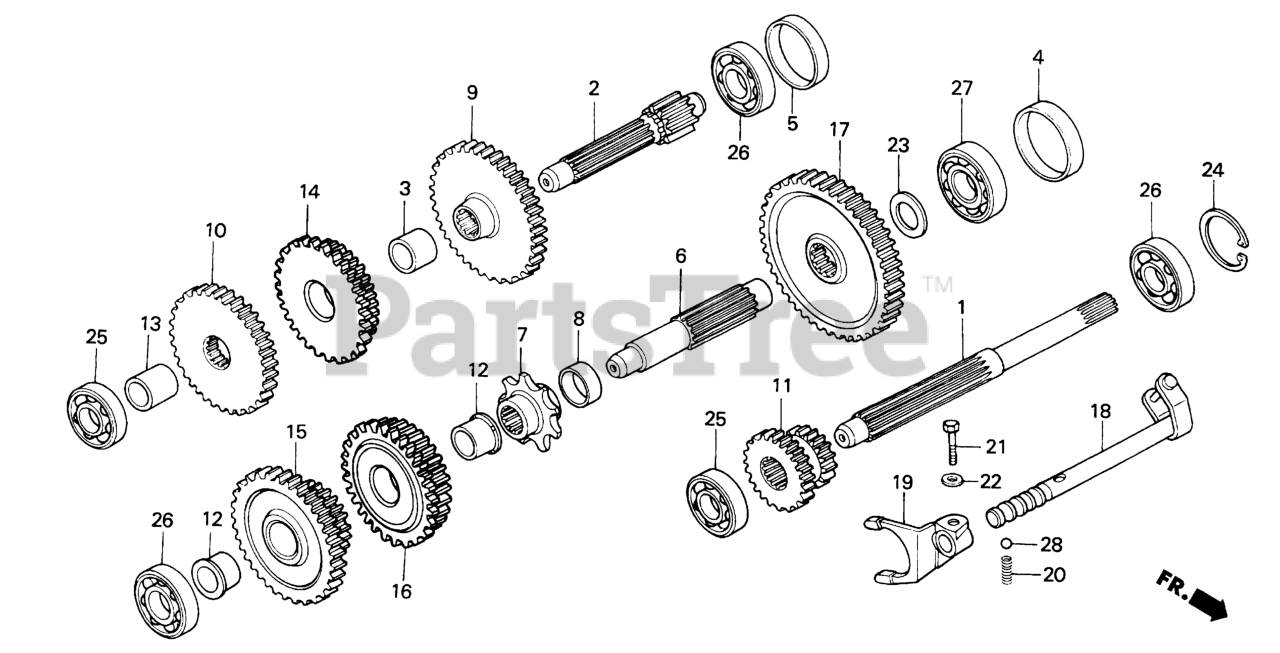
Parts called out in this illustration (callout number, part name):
1	SHAFT, INPUT
2	COUNTERSHAFT (13T)
3	COLLAR B, COUNTERSHAFT
4	COLLAR A, DISTANCE
5	COLLAR B, DISTANCE
6	SHAFT, FINAL
7	SPROCKET, DRIVE (9T)
8	COLLAR, FINAL SHAFT
9	GEAR, COUNTERSHAFT FIRST (50T)
10	GEAR, COUNTERSHAFT SECOND (45T)
11	GEAR, CHANGE (18T/23T)
12	COLLAR, IDLE GEAR
13	COLLAR, COUNTERSHAFT IDLE GEAR
14	GEAR, REVERSE COUNTER IDLE (26T/21T)
15	GEAR, REVERSE IDLE (49T/31T)
16	GEAR, REVERSE FINAL IDLE (26T/25T)
17	GEAR, FINAL (58T)
18	SHAFT, SHIFT FORK
19	FORK, SHIFT
20	SPRING, BALL SETTING
21	BOLT, SPECIAL (6X21)
22	WASHER, CONICAL SPRING (6MM) Use up to Frame SN 3500085.
23	WASHER (17MM)
24	CIRCLIP (INNER) (35MM)
25	BEARING, RADIAL BALL (6002)
26	BEARING, RADIAL BALL (6202)
27	BEARING, RADIAL BALL (6203)
28	BALL, STEEL (#8) (1/4)
